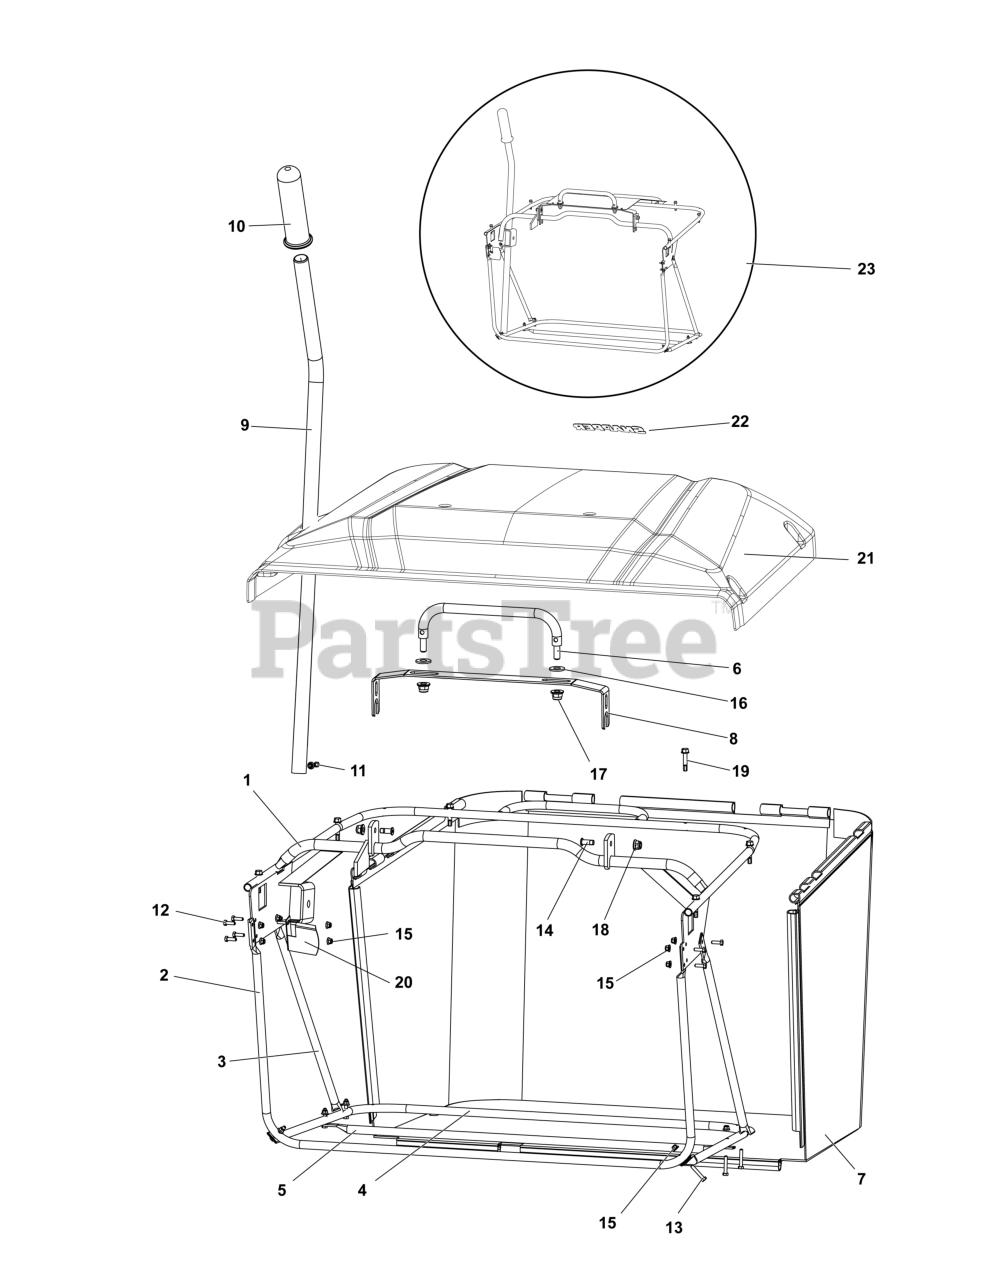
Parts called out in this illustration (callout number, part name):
5	TUBE, Connecting
7	CATCHER, Grass
8	PLATE, Reinforcement
22	DECAL, Brand
23	FRAME, Catcher, Grass
